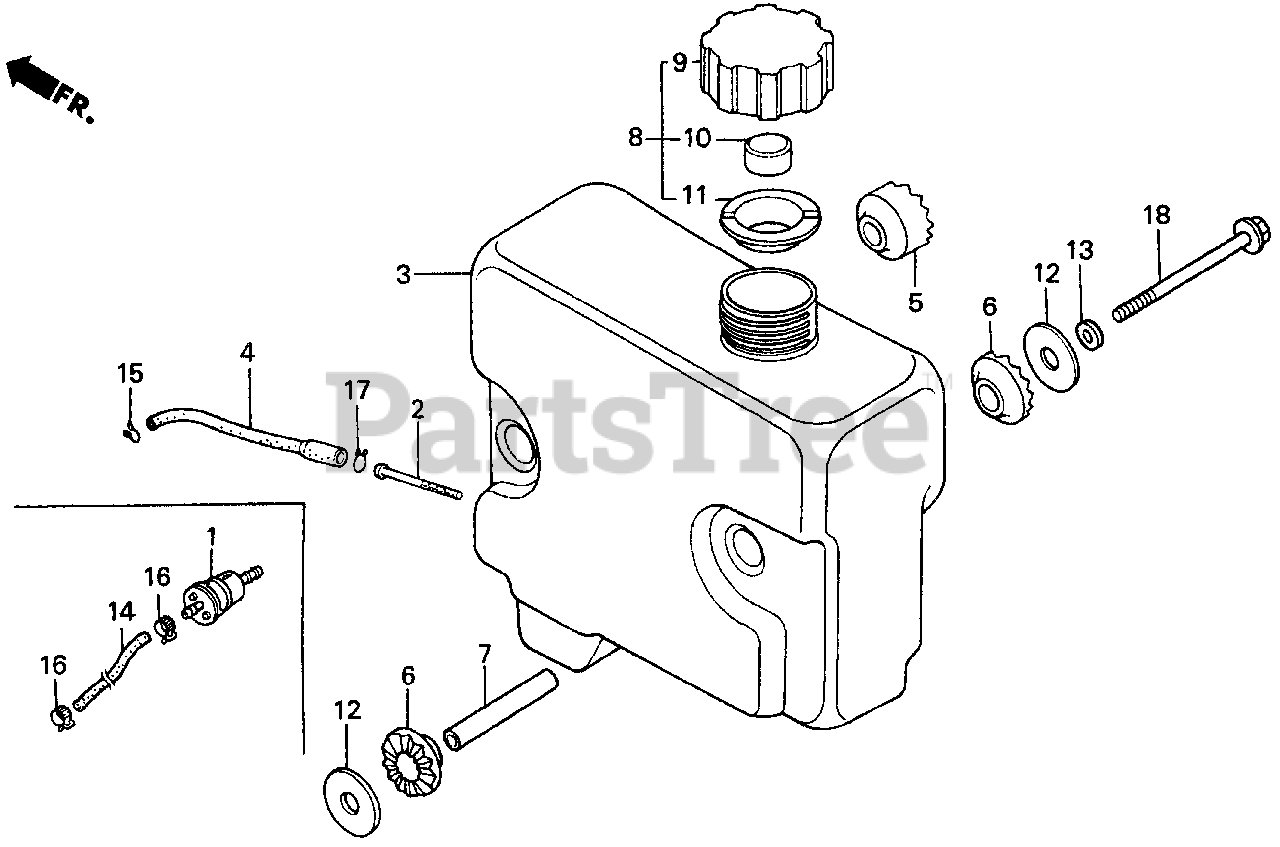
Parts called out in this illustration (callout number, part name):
2	FILTER, FUEL
3	TANK, FUEL
4	TUBE, FUEL
5	RUBBER B, TANK MOUNTING
6	RUBBER B, TANK MOUNTING
7	COLLAR, TANK SETTING
8	CAP ASSY., FUEL TANK
9	BODY, FUEL CAP
10	SPONGE, FUEL CAP BREATHER
11	GASKET, FUEL CAP
12	WASHER, TANK MOUNTING
13	WASHER, PLAIN (8MM)
15	CLIP, TUBE (B8)
17	CLIP, TUBE (C11)
18	BOLT, FLANGE (8X95)
